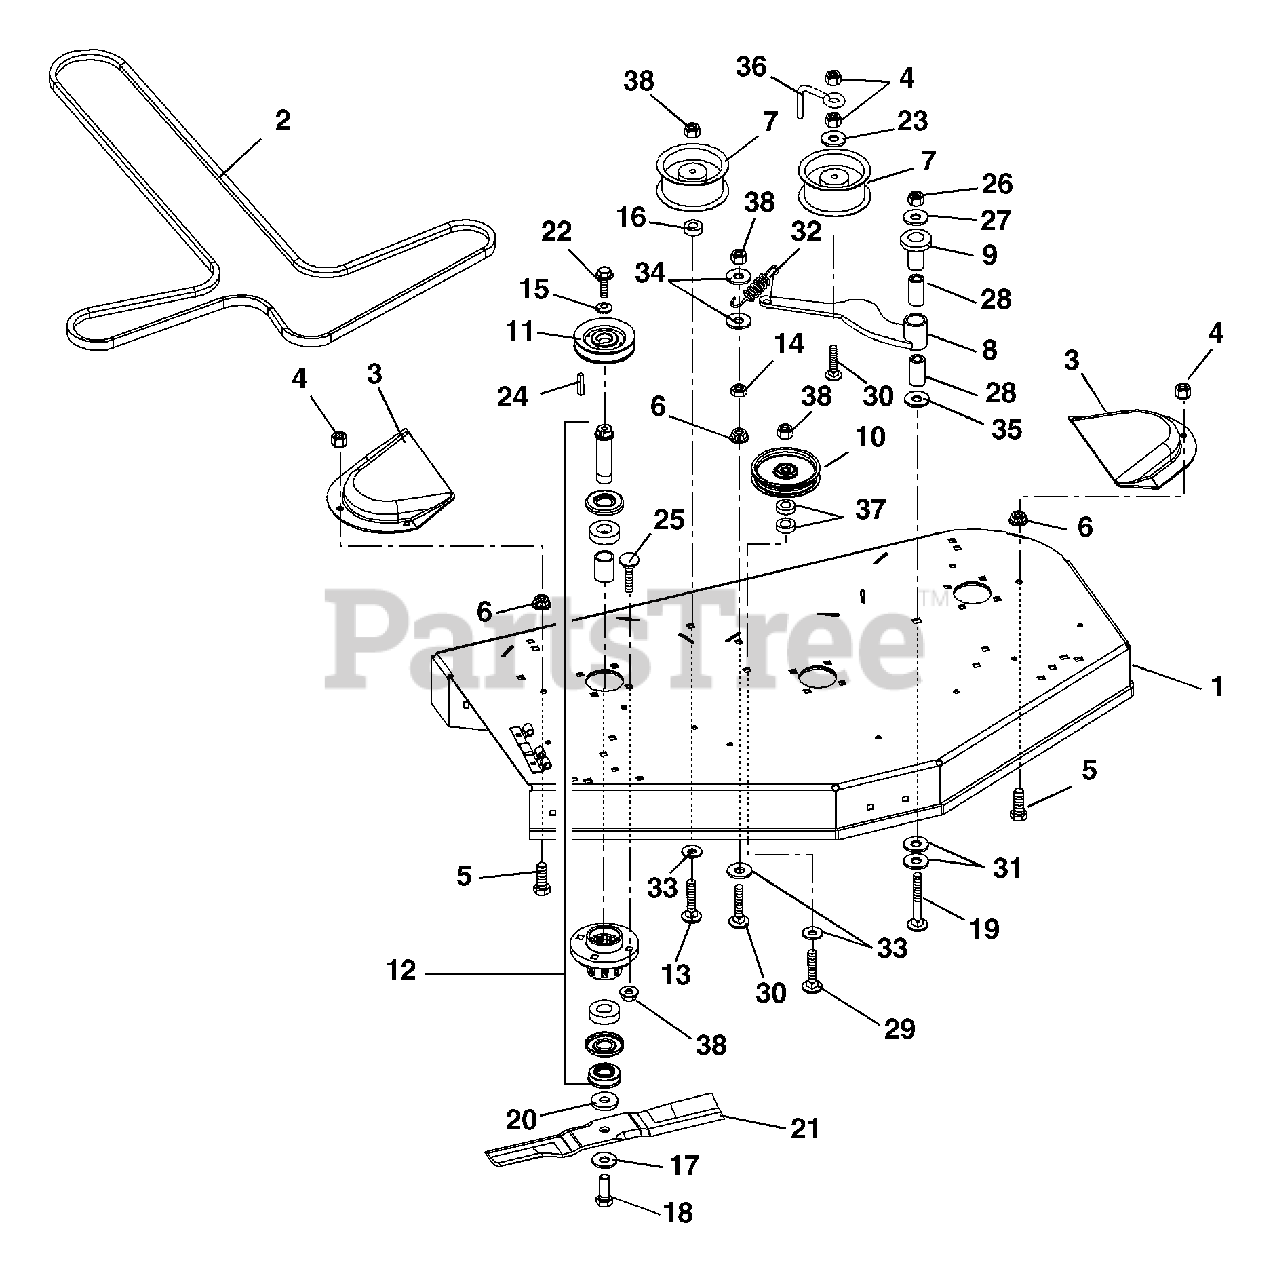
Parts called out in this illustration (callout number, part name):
1	40" MOWER DK W/DECALS C-L2078
2	V-BELT, HA-WRAPPED
4	@NUT-LK-NYL-FLG .38-16 YWZC
5	BLT-HEX .38-16X1.00 GR5 BKZC
6	@NUT-SPNLK-FLG .375-16 YWZC
7	IDLER FLANGED 3.50
8	WELDMENT, IDLER ARM
9	BEARING, PEDESTAL
10	IDLER-FLAT 4.00 X .38 NWHAMSHR
11	SHEAVE, SPINDLE - 4.00 DIA.
12	ASSEMBLY, SPINDLE
13	@BLT-RDHDSQNK .38-16X2.25 G5YZ
14	@NUT-LK-CTR-JAM .375-16 YWZC
15	WASHER, CUPPED SERRATED, .375
16	SPACER, .39 X 1.50 X .380
17	WSHR-BLVL .669X1.535X.138
18	BLT-HEX .62-18X1.75 GR8 YWZC
19	@BLT-RDHDSQNK .50-13X3.75 G5YZ
20	WSHR-FLT .640X1.75X.250 YWZC
21	MOWER BLADE, 13.94"
22	BLT-HEX .38-16X1.00 YZ GR8
23	WSHR-FL-STL .406X1.00X.188 YWZ
24	KEY, SQ .25 X .38 X .25
25	@BLT-RDHDSQNK .38-16X1.25 G5YZ
26	@NUT-LK-TOP-FLG .50-13 YWZC
27	WSHR-FL-STL .531X1.250X.10 YWZ
28	BRG, 1.00 X 1.12 X .75
29	@BLT-RDHDSQNK .38-16X1.75 G5YZ
30	@BLT-RDHDSQNK .38-16X2.75 G5YZ
31	WSHR-FL-STL.755X1.375X.062YWZC
32	SPRING, EXTENSION
33	@WSHR-FL-STL.563X1.38X.109YWZC
34	WSHR-FL-STL .375X1.125X.065YWZ
35	WSHR-FL-STL .515X1.625X.250 YZ
36	FINGER - BELT
37	WSHR-FL-STL .380X1.50X.125YWZC
38	@NUT-LK-NYL-FLG .38-16 YWZC
